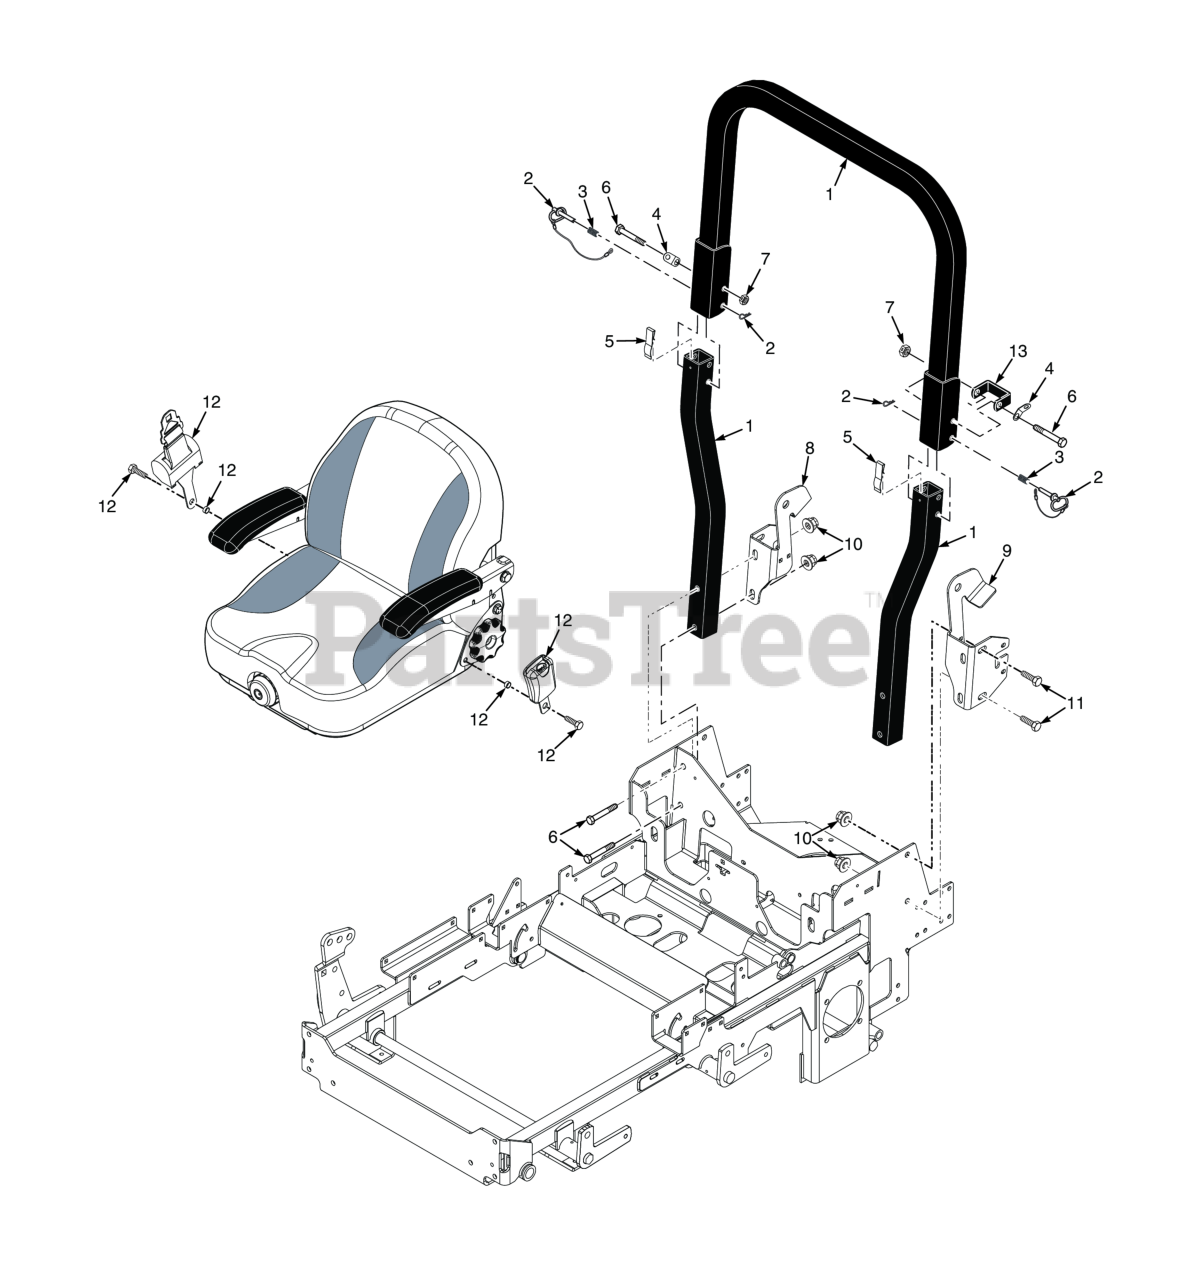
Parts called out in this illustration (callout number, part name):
1	ROPS Assembly, Foldable
2	Pin Assembly, ROPS Hinge
3	Spring, ROPS
4	Clip, ROPS
5	Spring, ROPS Anti-Rattle
6	Bolt, Hex Head, 1/2-13 x 3-1/4"
7	Locknut, Hex 1/2-13 Center Lock
8	ROPS Mount, RH, 22 & 23FX/ 23CV / 24FT / 26FT-EFI / 25CV-EFI
9	ROPS Mount, LH, 22 & 23FX / 23CV / 24FT / 26FT-EFI / 25CV-EFI
10	Nut, Elastic Stop 1/2-13, (STT-52 & STTII-52)
11	Bolt, Hex Head 1/2-13 x 1-1/4"
12	Seat Belt Kit (Suspension Seat)
13	Stop, ROPS
